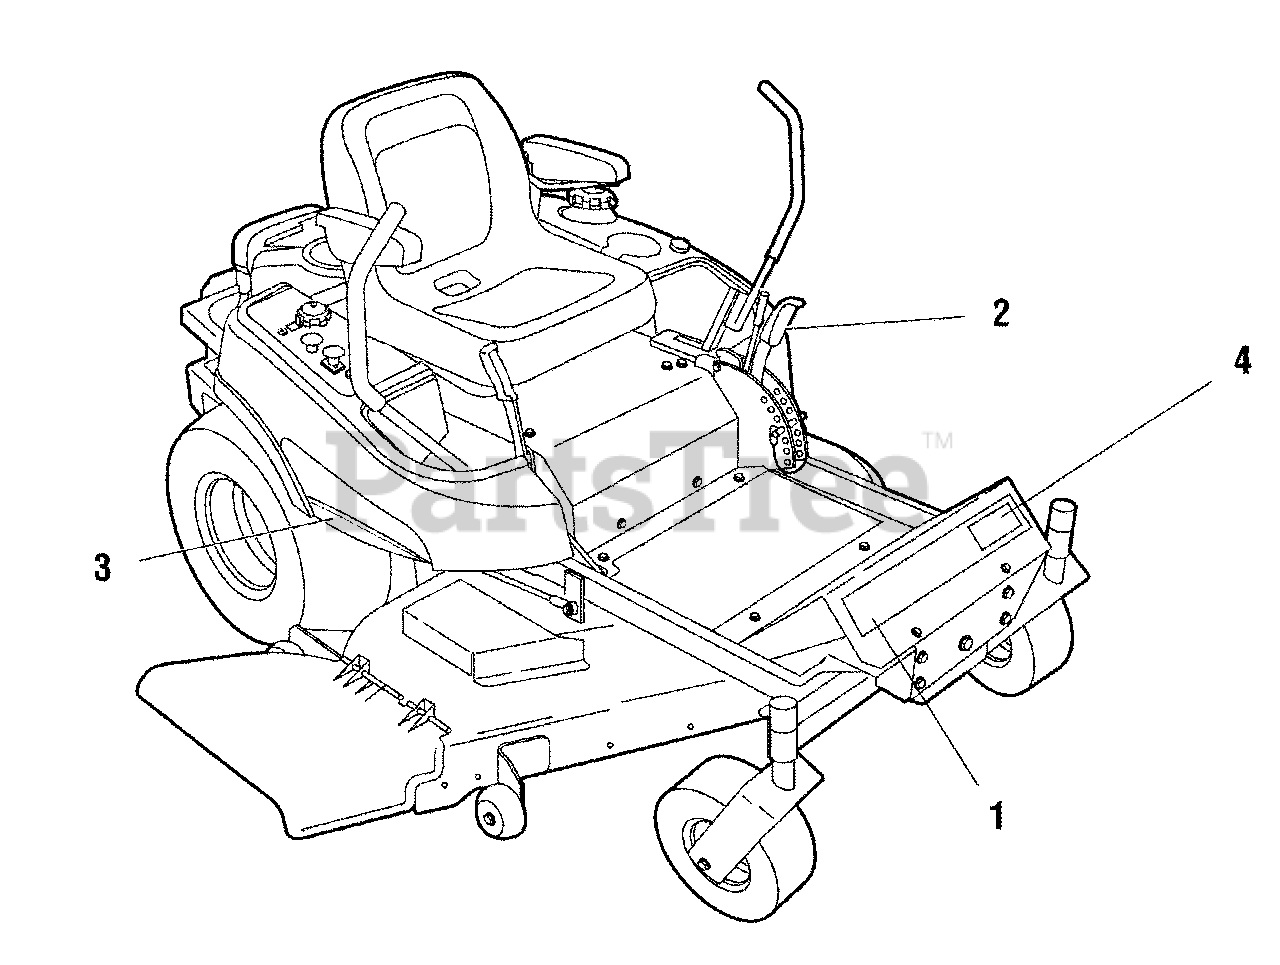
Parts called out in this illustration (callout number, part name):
1	DECAL, MASSEY STRIPE
2	DECAL, MASSEY, BADGE, LH
3	DECAL, MASSEY, BADGE, RH
4	DECAL, ZT1844
4	DECAL, ZT2050
